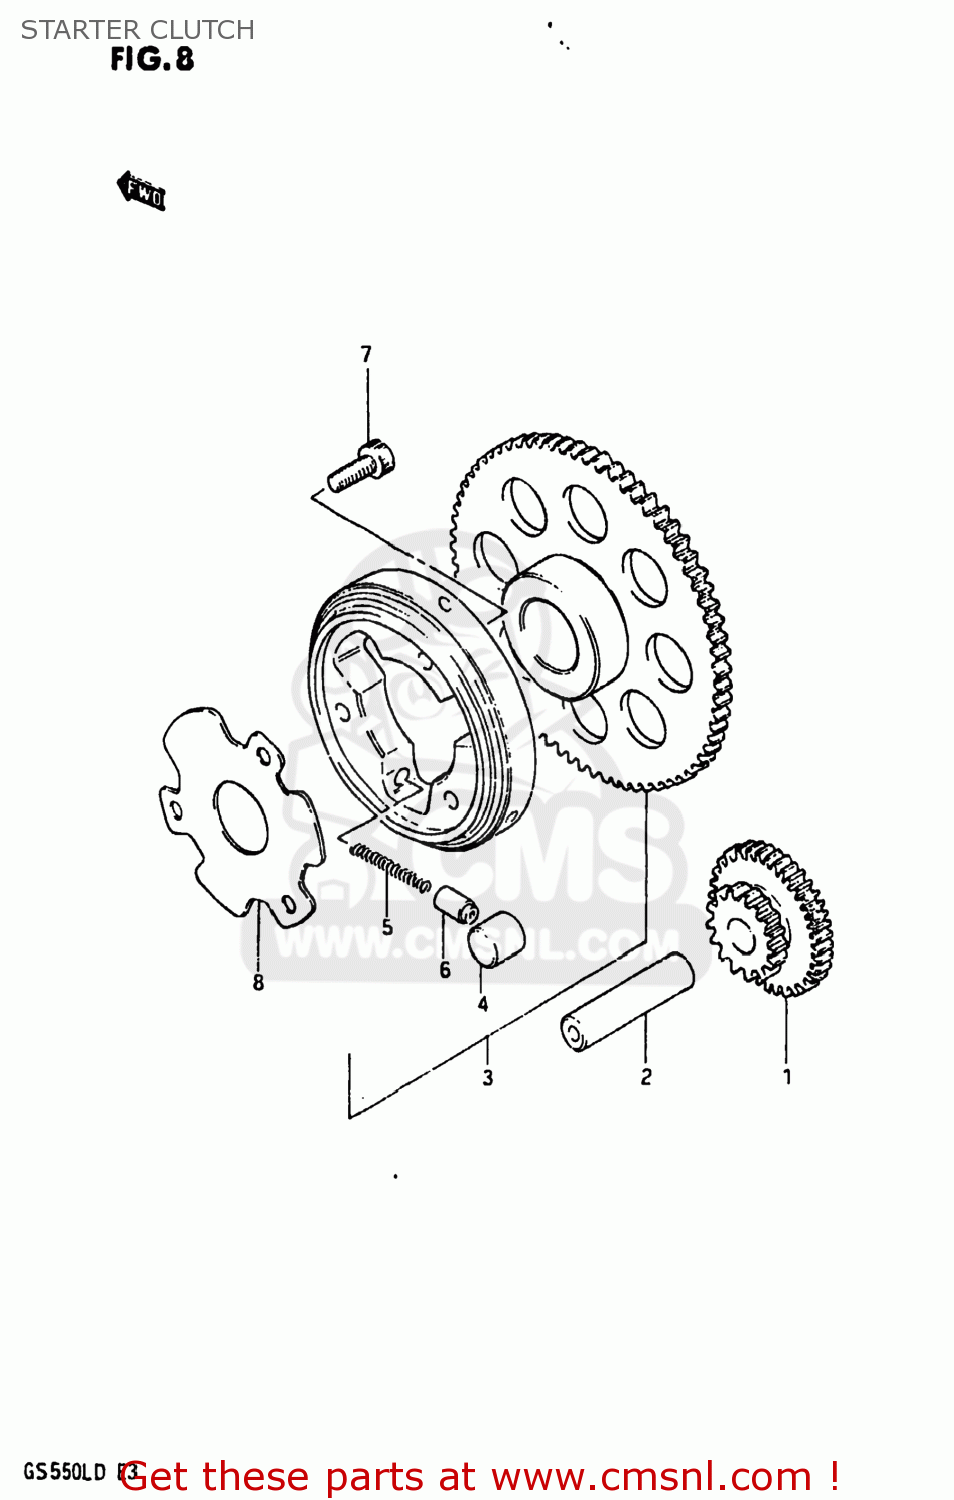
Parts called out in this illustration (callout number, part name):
1	GEAR,STARTER IDLE
2	PIN(7.4X13X56)
3	CLUTCH SET,STARTER
4	PIN(14X13)
5	SPRING
6	PIECE,PUSH
7	BOLT
8	SHIM,STARTER CLUTCH HUB
